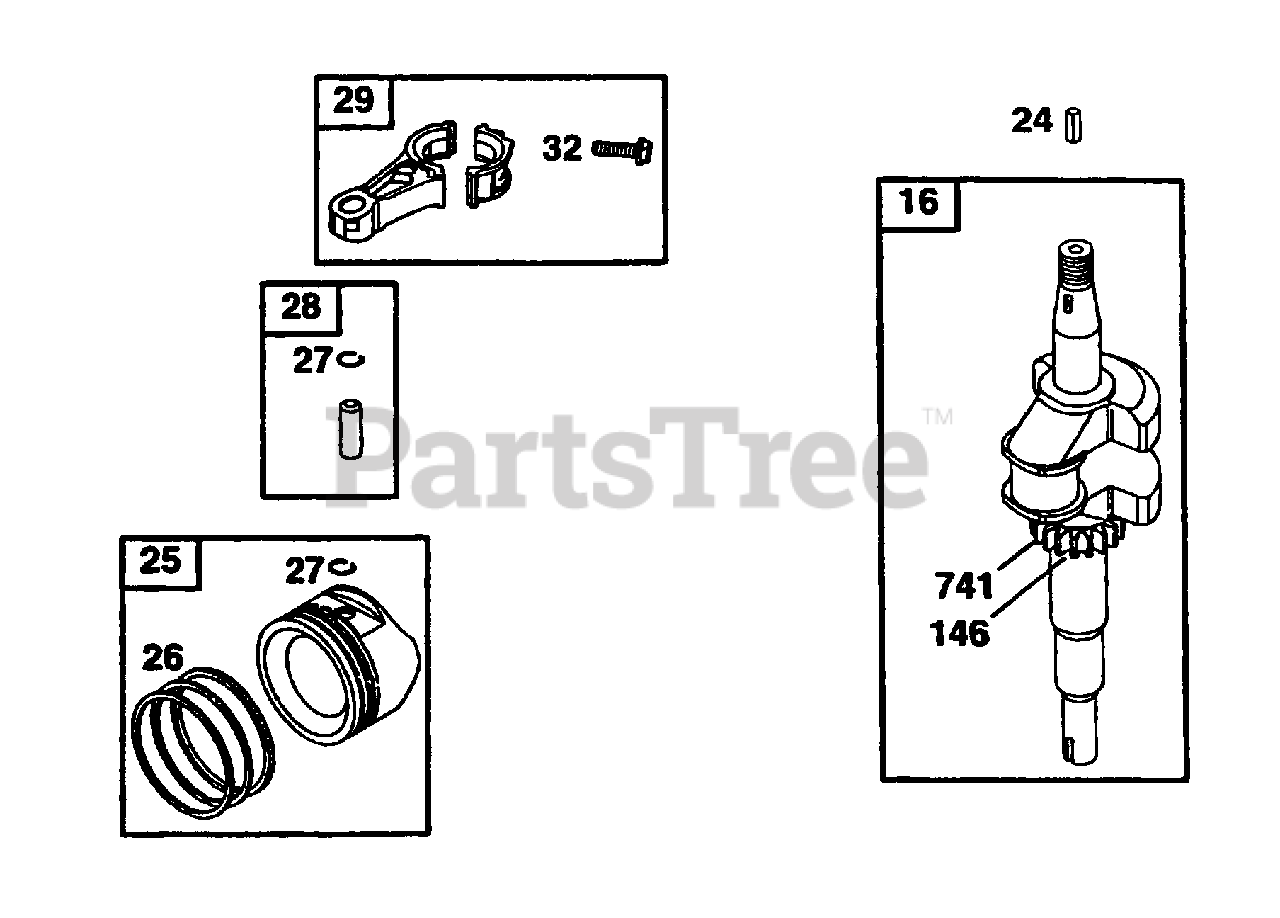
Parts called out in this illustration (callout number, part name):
16	Crankshaft
24	Flywheel Key
25	Piston Assembly (Standard)
26	Ring Set (Standard)
27	Piston Pin Lock
28	Piston Pin
29	Connecting Rod
32	Connecting Rod Screw
146	Timing Key
741	Timing Gear
